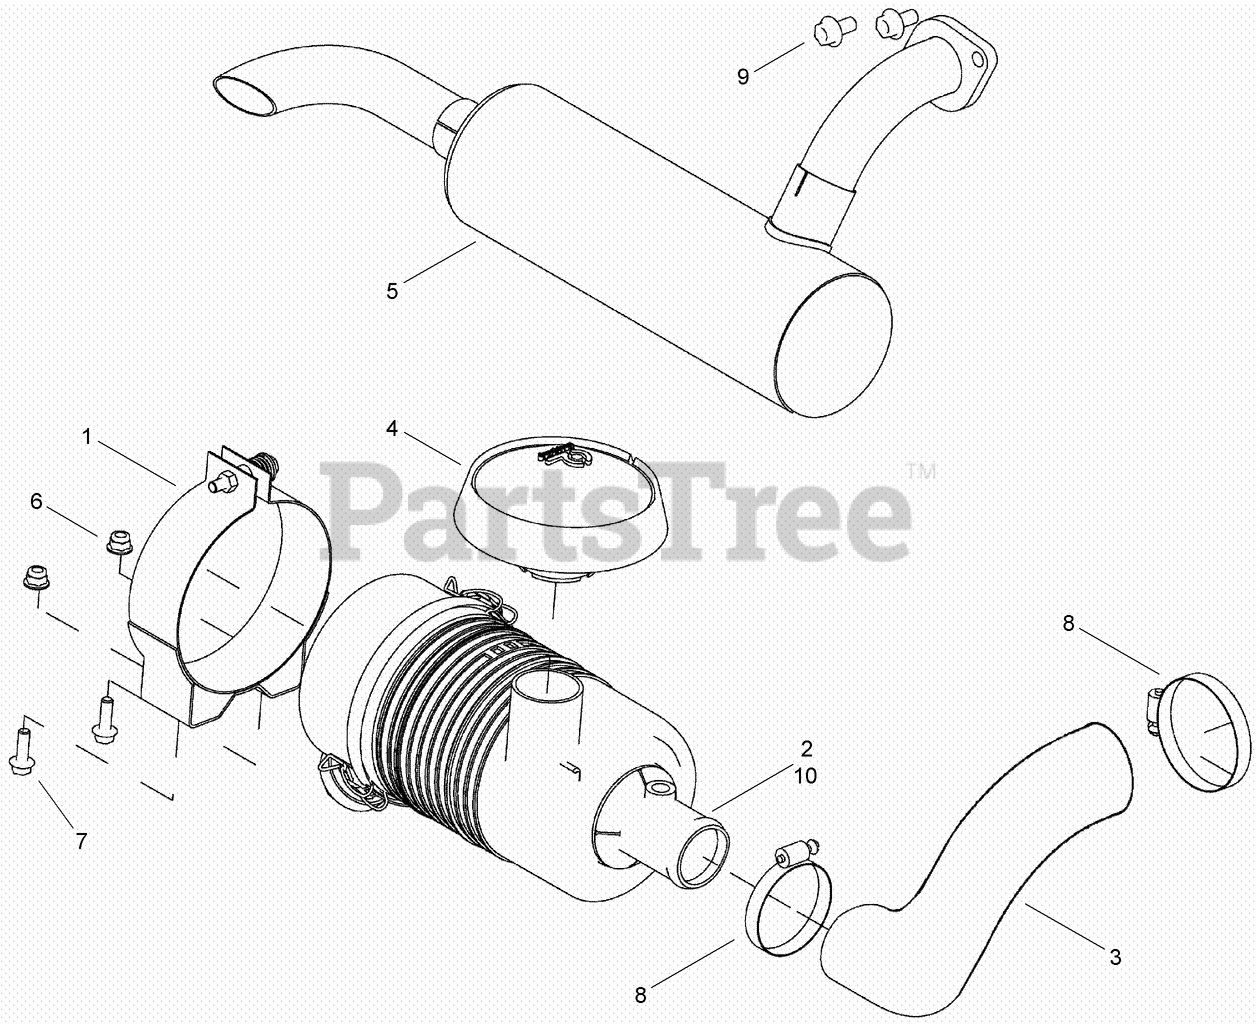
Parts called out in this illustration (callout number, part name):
1	BAND-AIR CLEANER
2	ASSEMBLY - Air Cleaner
3	HOSE - Air Cleaner
4	HOOD-RAIN
5	MUFFLER - Exhaust
6	NUT-TORQUE, PREVAILING
7	SCREW-HH
8	CLAMP-TORQUE, CONSTANT
9	SCREW, METRIC FLANGE w/BODY - M10 x 20
10	SWITCH-PRESSURE, VACUUM
